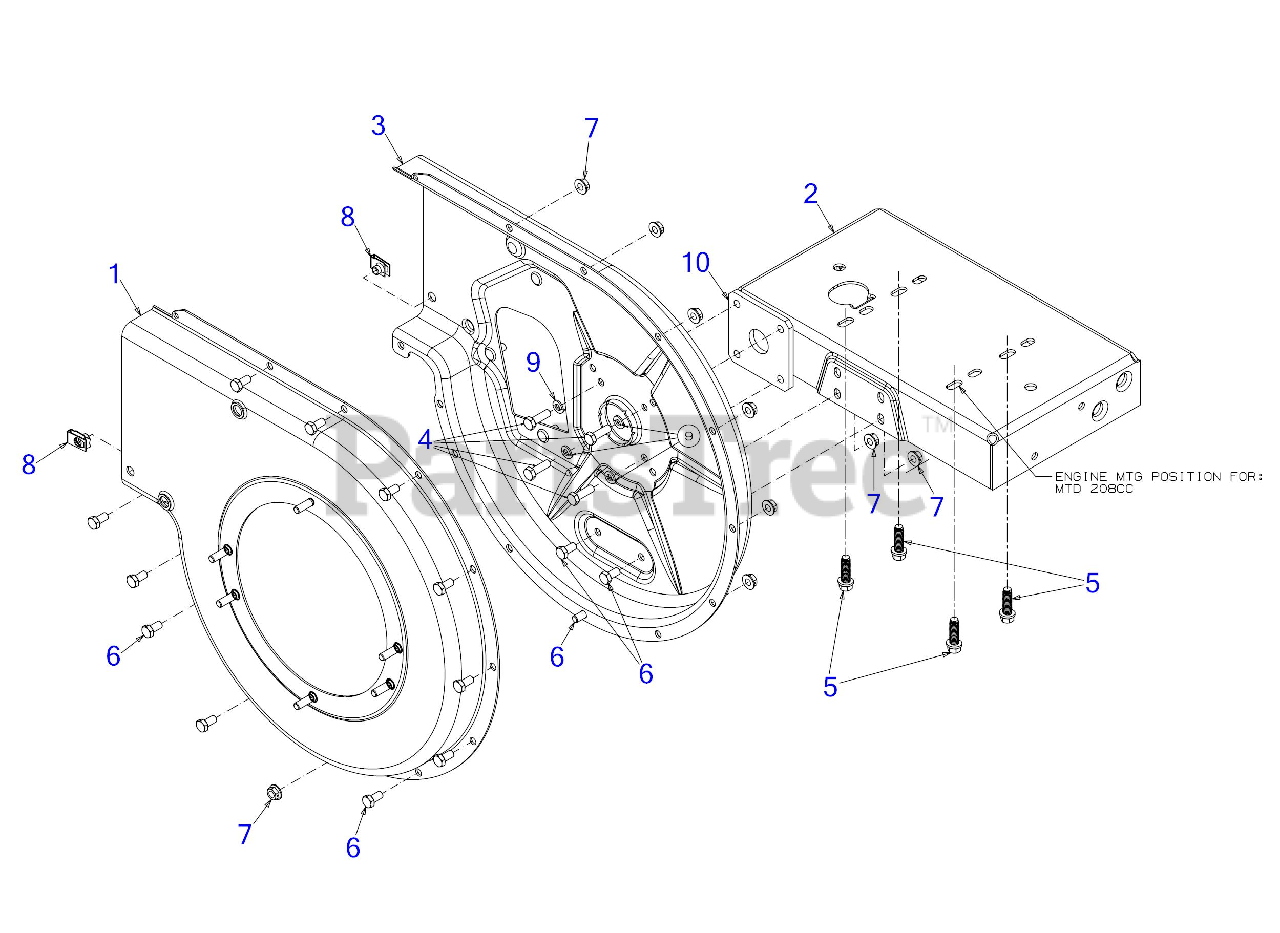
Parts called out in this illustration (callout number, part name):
4	HEX HEAD CAP SCREW 5/16-24 x 1.00 GR5
5	SCREW 3/8-16 x 1.250
6	SCREW 5/16-18X .625 GR5
7	HEX FLANGE NUT
8	U-NUT
9	LOCK WASHER 5/16
10	ENGINE PLATE
